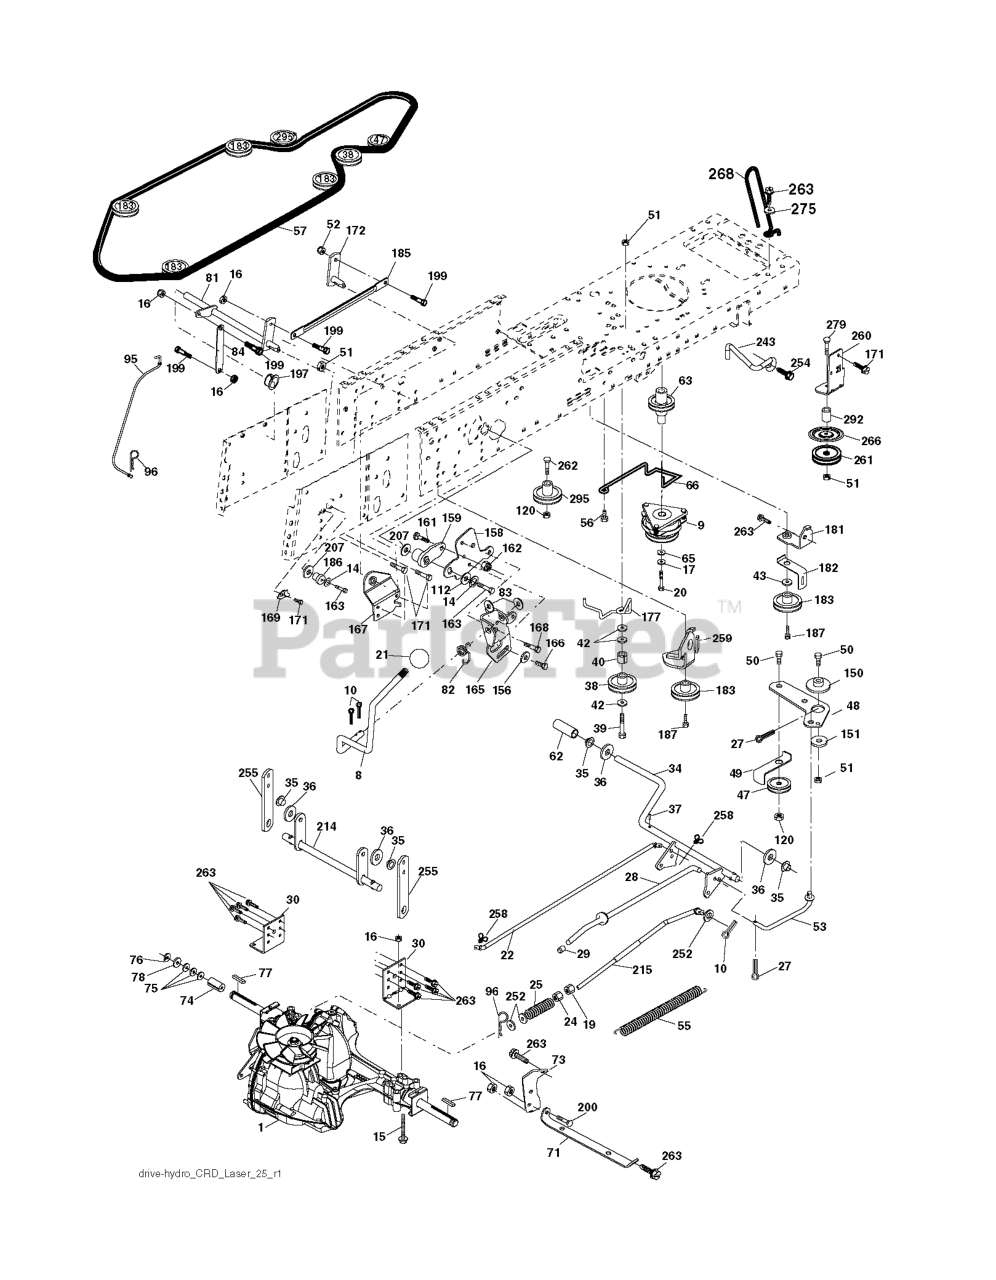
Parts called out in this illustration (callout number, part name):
8	ROD SHIFT FENDER ADJUST LT
9	CLUTCH.ELECTRIC.OGURA.EURO.
10	PIN COTTER
14	LOCKWASHER
15	BOLT HEX 5/16-18 GR 5
16	NUT.71038.31-18.HEX.NYLOCK
19	NUT
20	BOLT HEX 7/16-20X4-1/4"
21	KNOB.DUCKHEAD.1/2
22	ROD
24	NUT
25	SPRING BRAKE ROD
27	COTTER PIN
28	ROD, PARKING BRAKE
29	CAP
30	BRKT, TRNSXLE MNT 20"
34	SHAFT, FOOT PEDAL
35	BEARING.NYLON
37	DRIVE PIN
38	PULLEY.FLAT
42	WASHER
47	IDLER PULLEY
48	BELLCRANK, CLUTCH
49	RETAIN BELT
50	BOLT.3/8-16X1.50
52	LOCKNUT
53	LINK.CLUTCH.7.66.2005
55	SPRING, RETURN LT
56	SCREW.3/8-16
57	V-BELT 113"
62	PEDAL COVER T
63	PULLEY.ENGINE.CVX.LT
65	LOCKWASHER
66	KEEPER BELT ENGINE
71	STRAP TORQUE LH HYDRO
73	STRAP TORQUE RH HYDRO
74	SPACER AXLE
77	SQUARE KEY
81	ASM.CROSS.SHAFT.REAR.CRD.0510
82	SHIFT SPRING
83	WASHER
84	LINK.PNT.TRANSAXLE.0510.CRD
95	LINK
96	RETAINER M
120	NUT LOCK FLG 3/8-16 UNC
150	BUSHING.BELLCRANK.GRD.DR
151	WASHER 12/32X2X10GA
156	WASHER.SRRTD.5/16
158	BRACKET
159	RB HUB.SHIFT
161	BOLT
162	NUT.CROWNLOCK.1/4
165	RP BRACKET
166	CAPSCREW.HXHD.FLG.5/16-18X.625
167	BRACKET.SUPT.SHIFT.CRD
168	BOLT.SHOULDER.5/16-18X
169	PLATE.FASTENING.CROSS.SHAFT
172	LINK
181	BRACKET
182	BELT GUIDE
183	PULLEY.V-IDLER.GRND.DR
185	LINK
186	HUB.TAPERED.ROUND.CRD
187	BOLT.5/16-18X1.25
197	NYLINER SNAP 5/8" ID
199	BOLT SHOULDER 5/16-18 UNC
207	WASHER NYL
214	LEVER
215	ROD
243	BRACKET, ANTI-ROTATION
252	WASHER
254	SCREW 3/8-16X1
255	SHAFT
258	CLIP RETAINER
259	BRACKET
261	FLAT IDLER PULLEY
263	SCREW, 3/8-16X3/4
266	PROTECTOR
268	GUARD MUFFLER
275	WASHER
292	SPACER
295	PULLEY IDLER COMPOSITE
